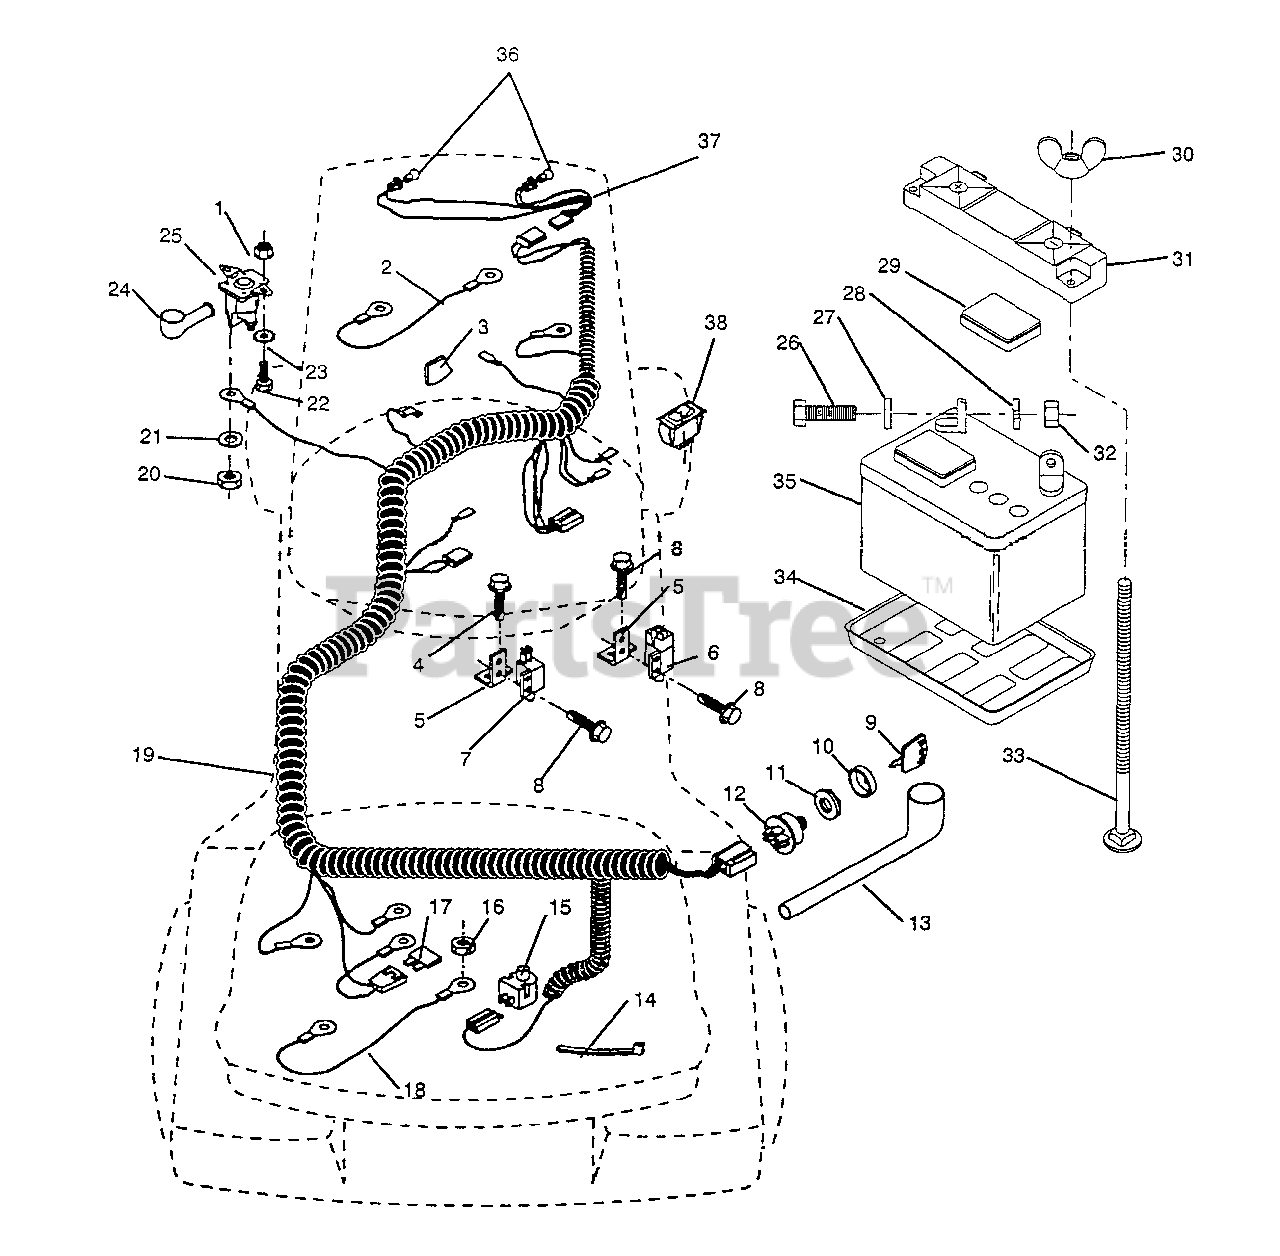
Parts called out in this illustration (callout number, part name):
1	Nut Hex Keps 1/4-20
2	Assembly, Cable
3	Stop, Choke
4	Screw, Hex Wsh. Tap #10-16 x 1/2
5	Bracket, Switch
6	Switch, Interlock
7	Switch, Interlock
8	Screw, Tap Hex Hd. # 10-24 x 1/2
9	Key, Molded
10	Cover, Key Ignition
11	Nut, Ignition
12	Switch, Ignition
13	Cover, Ignition Switch
14	Tie, Cable
15	Switch, Plunger
16	Keps, Nut 5/16-18
18	Assembly, Cable
19	Harness, Ignition
20	Nut, Hex Jam 1/4-20
21	Washer, Lock 1/4
22	Bolt Fin. Hex 1/4-20 UNC x 1/2 Gr. 5
23	Washer, Lock Ext. Tooth 1/4
24	Cover, Terminal
25	Solenoid
26	Bolt, Hex Hd. 1/4-20 UNC x 3/4
27	Washer 9/32 x 5/8 x 16 Ga.
28	Washer, Lock Hvy. Helical Spring 1/4
29	Cap, Battery
30	Nut, Plastic, Locking Wing 1/4-20
31	Guard, Terminal
32	Nut, Fin. Hex 1/4-20 UNC
33	Bolt, Carriage 1/4-20 UN C x 7-1/2
34	Tray, Battery
35	Battery
36	Bulb, Light
37	Harness, Light Socket
38	Switch, Light
